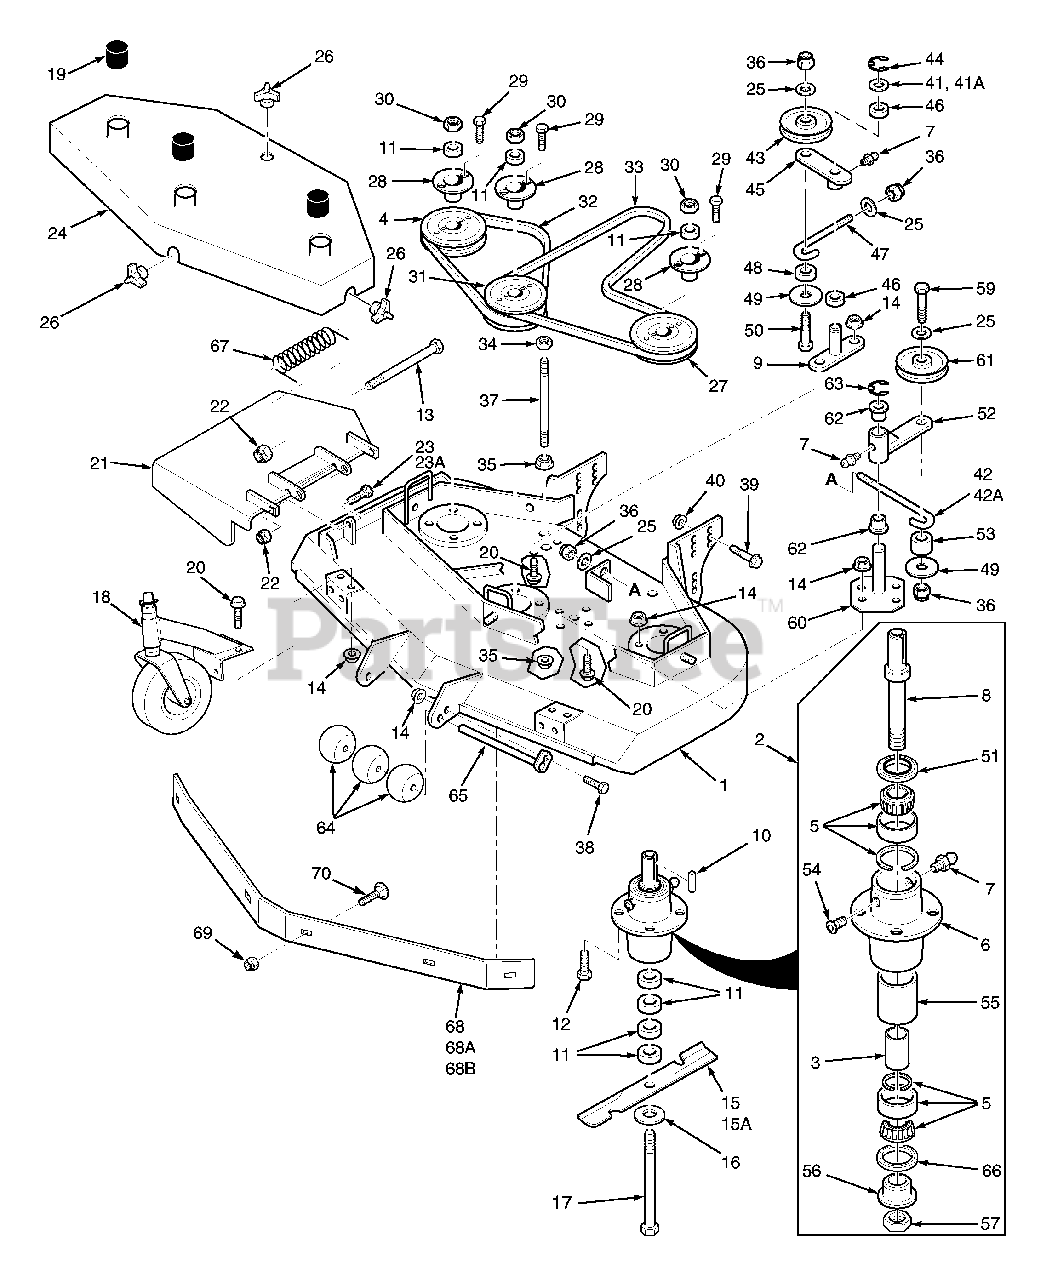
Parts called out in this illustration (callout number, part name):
1	Cutter Deck
2	Spindle Assembly
3	Spacer, Inside
4	Pulley
5	Tapered Bearing (Two)
6	Spindle Housing
7	Grease Fitting Str. 5/16
8	Spindle Shaft, Tapered Brng
9	Idler Pivot
10	Key, 1/4 x 1/4 x 2"
11	Spacer, Cutter Blade - Small
12	Bolt, 5/16-18 x 1-1/2" Hex Head Gr 8
13	Bolt, 5/16-18 x 4-3/4" Hex Head
14	Serrated Flange Nut, 5/16-18
15	Cutter Blade 18"
15A	Cutter Blade 18" Hi Lift
16	Flatwasher,5/8" (.688 x 1.75 x .134)
17	Hex Head Bolt, 5/8-11 x 9-1/2"
18	Caster Assembly (See Page 23)
19	Spindle Shield
20	Capscrew, 5/16-18 x 3/4"
21	Discharge Chute
22	Nut, 5/16-18 Elastic Elastic Stop
23	Bolt, 5/16-18 x 1-1/2" Hex Head (front)
23A	Bolt, 5/16-18 x 1-3/4" Hex Head (rear)
24	Belt Cover
25	Flat Washer, 3/8" Special
26	Wing Nut, 3/8-16 (Large)
27	Pulley
28	Tapered Hub
29	Bolt, 1/4-20 x 1" Hex Head
30	Nut, 5/8-11 Hex
31	Pulley, Double
32	Belt, RH Blade Drive
33	Belt, Blade Drive
34	Nut, 3/8-16, Nut Centerlock
35	Nut, 3/8-16, Serrated Flange
36	Nut, 3/8-16 Elastic Stop
37	Support, Belt Cover
38	Bolt, 5/16-18 x 1" Hex Head
39	Cpscrw,1/2-13 x 1" Ser Flng Hex Hd
40	Nut, 1/2-13 Spiralock
41	Flat Washer 3/4" Special
41A	Flat Washer 3/4" Special
42	J-Hook
42A	J-Hook
43	Idler Pulley, "V" Groove
44	Retaining Ring, 3/4" Ext."E"
45	Idler Arm Assy.
46	Bronze Bearing
47	J-Rod, Idler Pulley
48	Spacer, J-Rod
49	Washer, 3/8 x 1-1/2 x 16 ga.
50	Bolt, 3/8-16 x 2-1/4" Hex Head
51	Seal, Cutter Spindle
52	Idler Arm Assy
53	Spacer, J-Rod
54	Relief Fitting, Cutter Spindle
55	Spacer, Outside, Cutter Spindle
56	Spindle Bushing
57	Nut, Cutter Spindle
58	Wing Nut, 3/8-16
59	Bolt, 3/8-16 x 3-1/2" Hex Head
60	Idler Pivot
61	Idler Pulley, Belt Clutch
62	Bronze Bearing
63	Retaining Ring
64	Guide Roller
65	Roller Shaft
66	Seal, Cutter Spindle
67	Spring, Chute Return
68A	Baffle Weldment 52A
69	Nut, Hex Elastic Stop 3/8-16
70	Bolt, Carriage 3/8-16 x 1"
